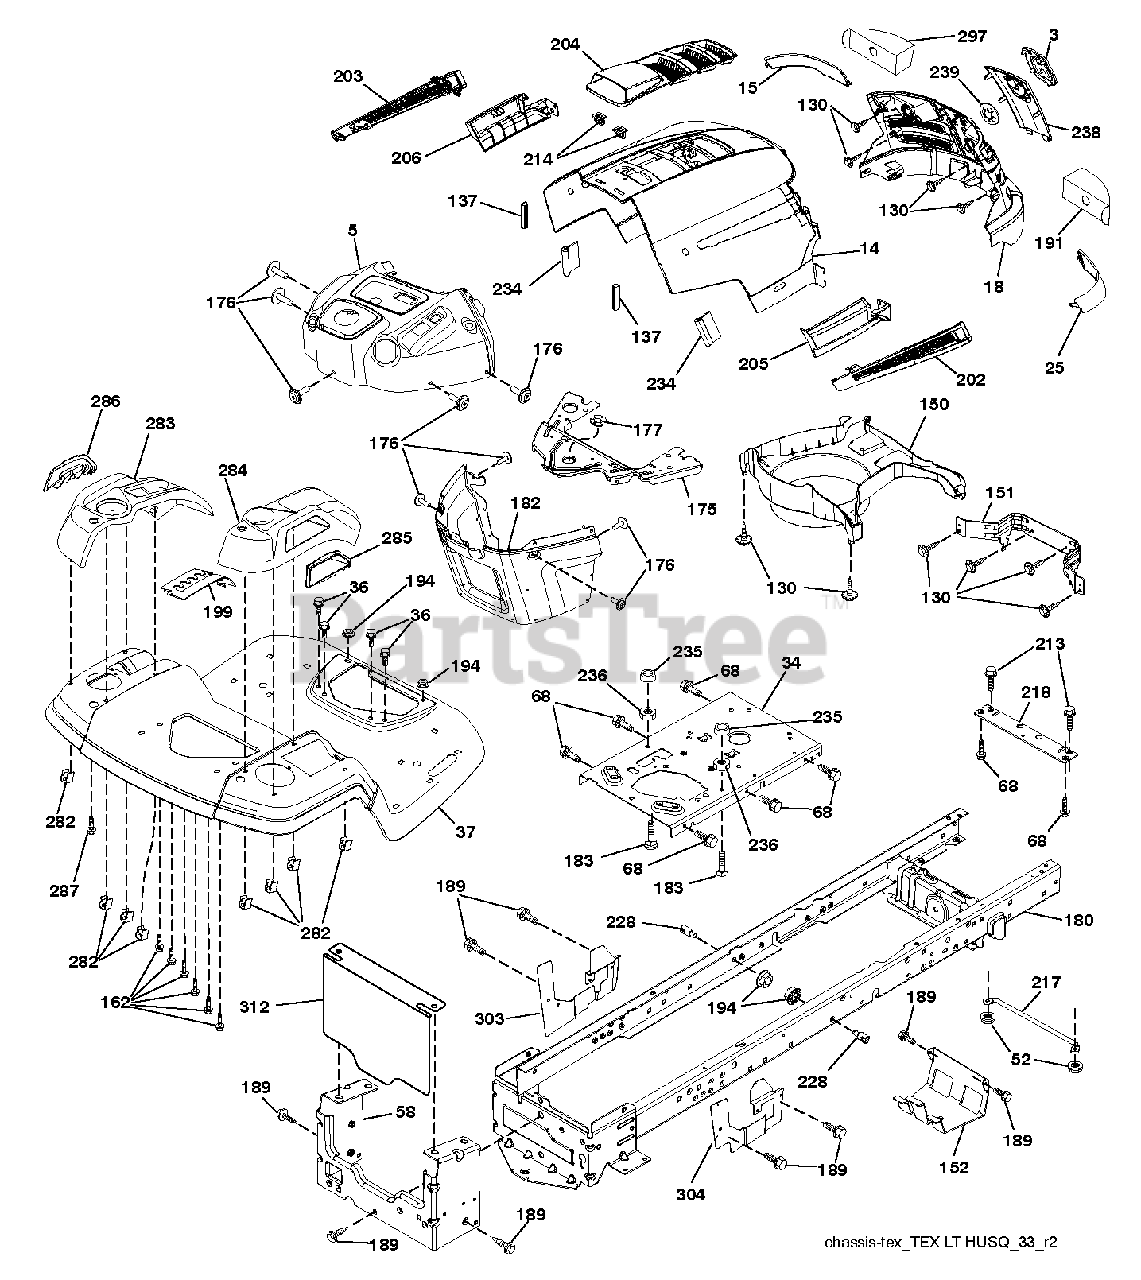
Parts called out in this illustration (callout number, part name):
3	RP LOGO
5	SUBASM.DASH.UPPER.W/BUMPER
14	HOOD.HUSQVARNA.LT.ORANGE
15	LENS.HUSQVARNA LT.RH
18	GRILLE.SVC.HUSQVARNA.GREY
25	LENS.HUSQVARNA LT.RH
34	PLATE.ENGINE.WELDED.CHASSIS
36	SCREW 5/16"
37	FENDER.TLT.FS.W/CUPHLD.ORANGE
52	LOCKNUT
58	DRAWBAR UPPER 2PC SMALL FENDER
68	SCREW LT
130	SCREW.#10 X 0.750.BOS
137	BUMPER DASH
151	BRACKET PIVOT
152	SHIELD.BROWNING.W/TEX
162	SCREW.HI-LO.CONSOLE
175	CROSSMEMBER
176	SCREW.#10-24X5/8.RN.QU
177	BUSHING STEERING
180	CHASSIS.WLDMNT.14GA.2PC.18".TI
182	DASH.LOWER.PREDATOR LT
183	BOLT.5/16-18X1-1/4 FULL THD
189	SCREW
191	INSERT.REFLECTIVE.RH.
194	NUT LOCK HEX FLANGE 5/16-18
199	PLATE.DECK.LIFT.HUSQ.LT
202	VENT.SIDE.HUSQVARNA.LT.RT
203	VENT.SIDE.HUSQVARNA.LT.LFT
204	SUBASM.TOP.VENT.HUSQ.LT
205	SKIRT.SIDE.HUSQVARNA.LT.RT
206	SKIRT.SIDE.HUSQVARNA.LT.LEFT
213	BOLT
214	CLIP.RETAINER.TINNER.
217	ROD.PIVOT.HOOD
218	X-PIECE.HOOD.STOP.NON/
228	STUD.FASTNER.W/ANTI-ROTATE
234	BUMPER.HOOD.TEX.HUSQVARNA
235	SPACER FENDER
236	NUT.CENTERLOCK.5/16-
238	TRIM.HUSQ LT.668
282	CLIP.RETAINER.CONSOLE.LT.HUSQ
283	CONSOLE.ASM.LFT.RSF.HUSQ.LT
284	CONSOLE.SHIFT.6SP.HUSQ.LT.498
285	CONSOLE INSERT RH
286	CONSOLE.INSRT.LH.HUSQ.LT.BLACK
287	SCREW 1/4X20
297	INSERT REFLECTIVE
303	SHIELD CHASSIS LEFT
312	SHIELD.PNT.DRAWBAR.FRENCH
